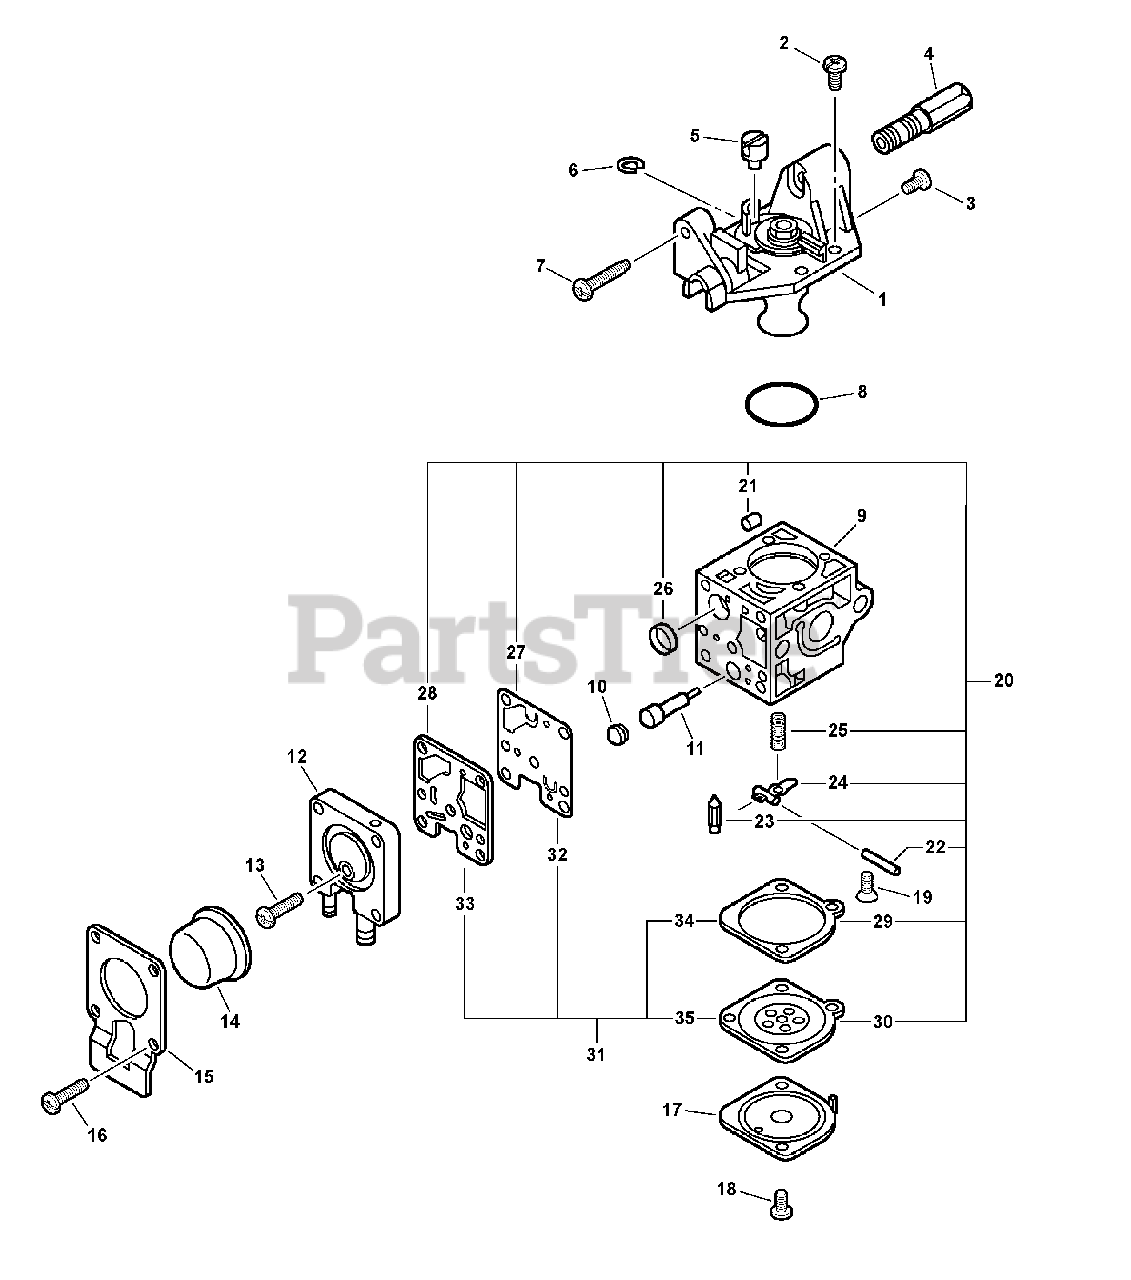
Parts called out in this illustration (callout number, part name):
1	Rotor Cover Asy
2	Screw, Rotor Cover Asy
3	Screw, Rotor Cover
4	Screw, Cable Adjust
5	Swivel
7	Screw, Throttle Adjust
9	Body, Carburetor
11	Needle - High Speed
12	Purge Base Asy
13	Screw, Purge Base Asy
14	Bulb, Purge
15	Retainer, Purge Bulb
16	Screw, Purge Bulb Retainer
17	Cover, Diaphragm
18	Screw, Diaphragm Cover
19	Screw, Metering Lever Pin
20	Repair Kit
21	Roller, Guide
22	Pin, Metering Lever
23	Valve, Inlet Needle
24	Lever, Metering
25	Spring, Metering Lever
26	Strainer
27	Diaphragm, Pump
28	Gasket, Pump
29	Gasket, Metering
30	Diaphragm, Metering
31	Diaphragm/Gasket Kit
32	Diaphragm, Pump
33	Gasket, Pump
34	Gasket, Metering
35	Diaphragm, Metering
